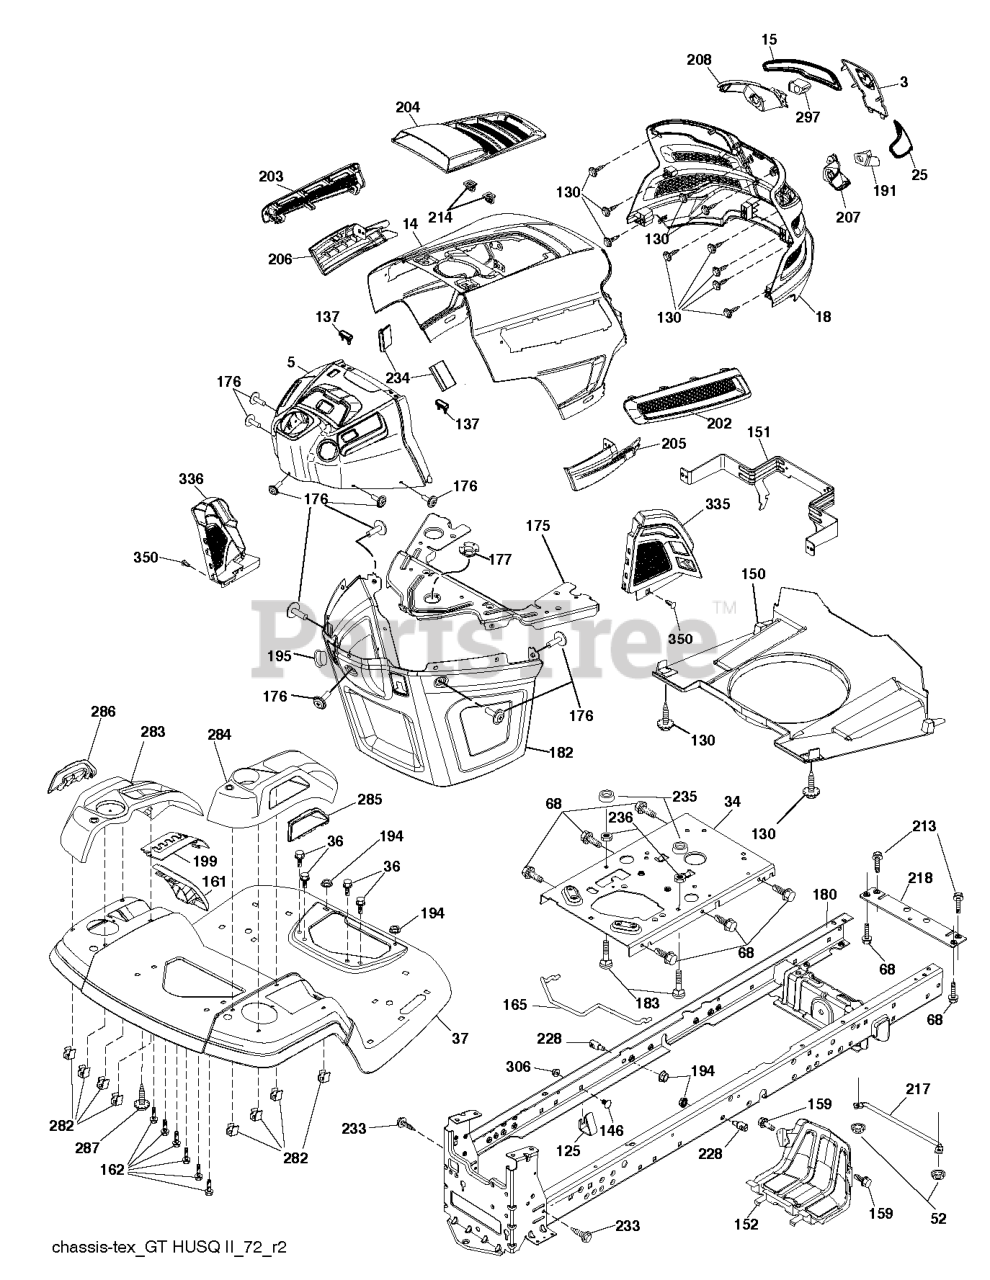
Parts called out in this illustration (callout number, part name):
3	APPLIQUE.SUBASM.GT.HUSQ.II
5	DASH.UPR.ASSY.GT2.SRVMNDER.PTO
14	HOOD.ASM.HUSQVARNA.GT.TEX.ORAN
15	LENS.HEADLIGHT.LH.GTII.2011
18	GRILLE.SUBASM.GT.HUSQ.II
25	LENS.HEADLIGHT.RH.GTII.2011
34	PLATE.ENGINE.WELDED.CHASSIS
36	SCREW 5/16"
37	FENDER.TLT.FS.W/CPH/FW/RSF.668
52	LOCKNUT
68	SCREW LT
130	SCREW.#10 X 0.750.BOS
137	BUMPER DASH
150	AIR.DUCT.GTV.BLACK
151	BRACKET.PIVOT.HOOD.GT.HUSQ.II
152	SHIELD.BROWNING.PNT.GT.V2
159	SCREW, 3/8-16X3/4
161	WINDOW.FUEL.LT.HUSQ.TEX.498
162	SCREW.HI-LO.CONSOLE
165	SUPPORT.TANK.REAR.W/TEX
175	PLATE.CROSSMEMBER.HUSQ
176	SCREW.#10-24X5/8.RN.QU
177	BUSHING, STEERING
180	CHASSIS
182	DASH.LOWER.COMMON.12V.ADAPTOR
183	BOLT.5/16-18X1-1/4 FULL.THREAD
191	INSERT.REFLECTIVE.RH.HUSQ.GTII
194	NUT LOCK HEX FLANGE 5/16-18
195	PLUG.HOLE.DASH.LOWER.12V.BLK
199	PLATE.DECK.LIFT.HUSQ.LT
202	VENT.SIDE.RH.GT.HUSQ.II.
203	VENT.SIDE.LH.GT.HUSQ.II.498
204	VENT.TOP.HUSQ.GT2
205	SIDE.TRIM.RH.GT.HUSQ.II
206	SIDE.TRIM.LH.GT.HUSQ.II.GRAY
207	BEZEL LIGHT.RH.GT.II.MYLAR
208	BEZEL LIGHT.LH.GT.II.MYLAR
213	BOLT
214	CLIP.RETAINER.TINNER.
217	ROD.PIVOT.HOOD
218	X-PIECE.HOOD.STOP.NON/
228	STUD.FASTNER.W/ANTI-ROTATE
233	BOLT.SHOULDER
234	BUMPER.HOOD.TEX.HUSQVARNA
235	SPACER FENDER
236	NUT.CENTERLOCK.5/16-
282	CLIP.RETAINER.CONSOLE.LT.HUSQ
283	CONSOLE.DECK.LIFT.R.SDFL.HUSQ
284	CONCOLE.CNTRL.PDL.HUSQ.LT.498
285	CONSOLE INSERT RH
286	CONSOLE.INSRT.LH.HUSQ.LT.BLACK
287	SCREW 1/4X20
297	INSERT.REFLECTIVE.LH.HUSQ.GTII
335	COVER.RH.CLOSE.OUT.BLACK
336	COVER-LH.LOWER.DASH.GT2.BLACK
337	CLIP.XMAS.TREE.ITW.2622-00
346	CLIP,INSULATOR
